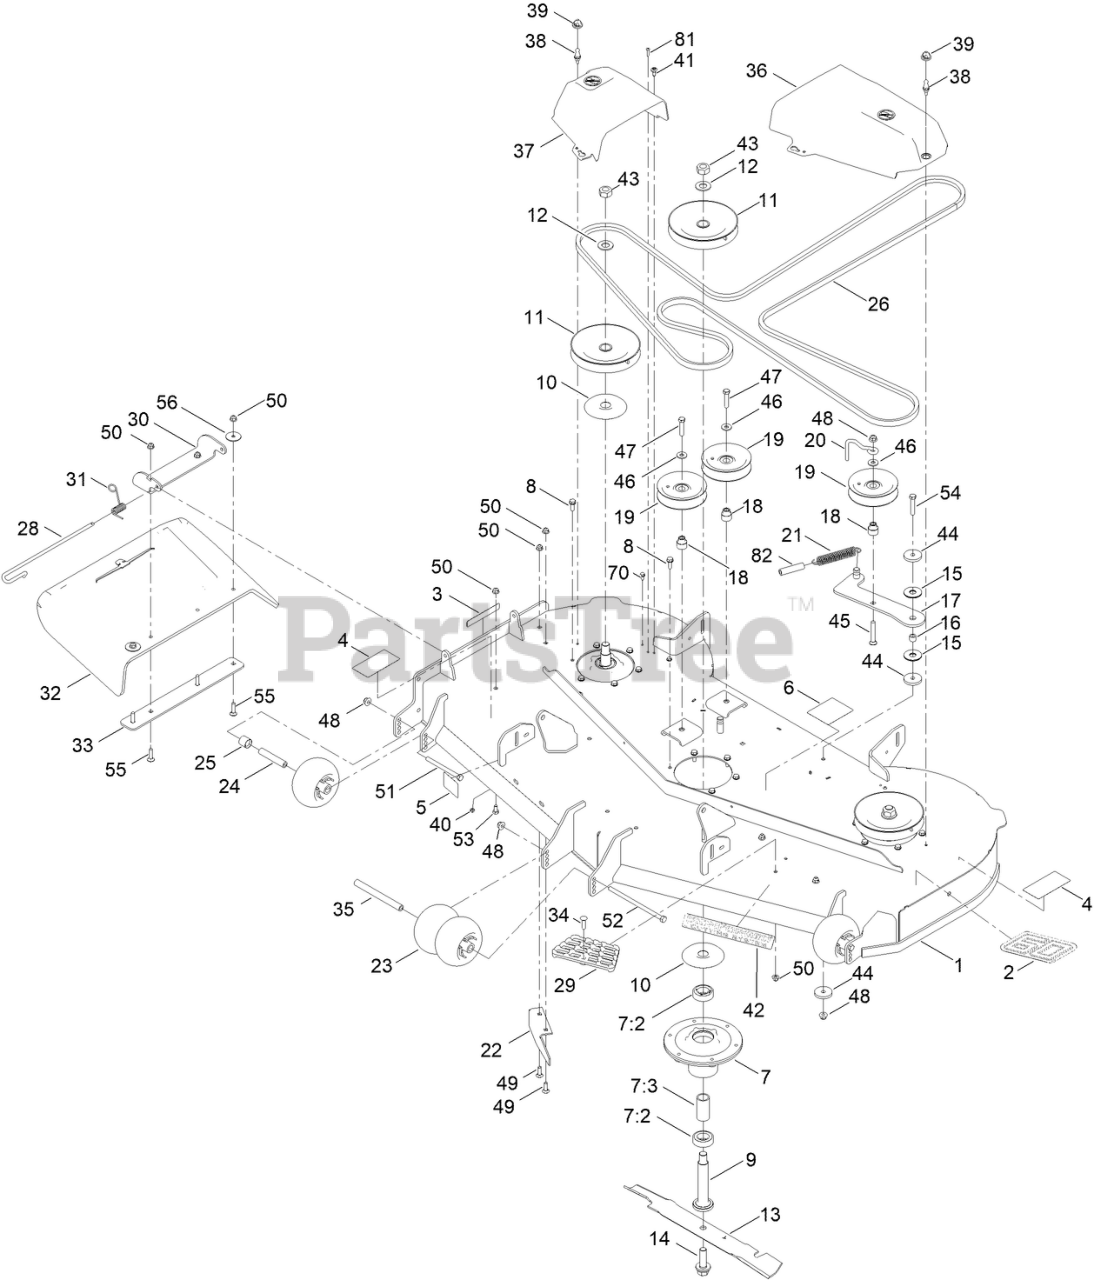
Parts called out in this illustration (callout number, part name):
1	60 IN DECK DECAL ASM
2	DECAL - DECK 60
3	DECAL-DANGER
4	DECAL-DANGER, DECK
5	DECAL-SCALP, ANTI
6	DECAL-ROUTING, BELT
7	SPINDLE ASM
7:2	BEARING-BALL
7:3	SPACER-BEARING
8	SCREW-TAPTITE
9	SHAFT-SPINDLE
10	SHIELD-BEARING
11	PULLEY
12	WASHER
13	BLADE-HI FLOW, 20.5 INCH
14	SCREW-BLADE
15	WASHER-FRICTION, COMPOSITE
16	SPACER
17	IDLER ARM ASM
18	BUSHING-IDLER
19	PULLEY-IDLER, FLAT
20	GUIDE-BELT, IDLER
21	SPRING-EXTENSION
22	BAFFLE-CUTOFF
23	ROLLER-SCALP, ANTI
24	TUBE-SPANNER
25	SPACER-AXLE, REAR
26	BELT-V
28	PIN-CHUTE
29	STEP-DECK
30	BRACKET-DEFLECTOR, UPPER
31	SPRING-TORSION
32	DEFLECTOR - MOLDED
33	PLATE-DEFLECTOR
34	BOLT-CARRIAGE
35	SPACER-WHEEL
36	COVER-BELT, LH
37	COVER-BELT, RH
38	STUD-BALL
39	GROMMET-BALL
40	NUT-LOCK
41	SCREW-SHOULDER
42	DECAL - IRON FORGED
43	NUT-HEX
44	WASHER-PLAIN
45	SCREW-CARR
46	WASHER-HARDENED
47	SCREW-HH
48	NUT-HF, NI
49	SCREW-CARR
50	NUT-HF, NI
51	SCREW-HH
52	SCREW-HH
53	SCREW-HH
54	SCREW-HH
55	SCREW-CARR
56	WASHER-FLAT
70	SCREW-HWH
81	RIVET-TRIFOLD
82	HOSE-BREATHER
